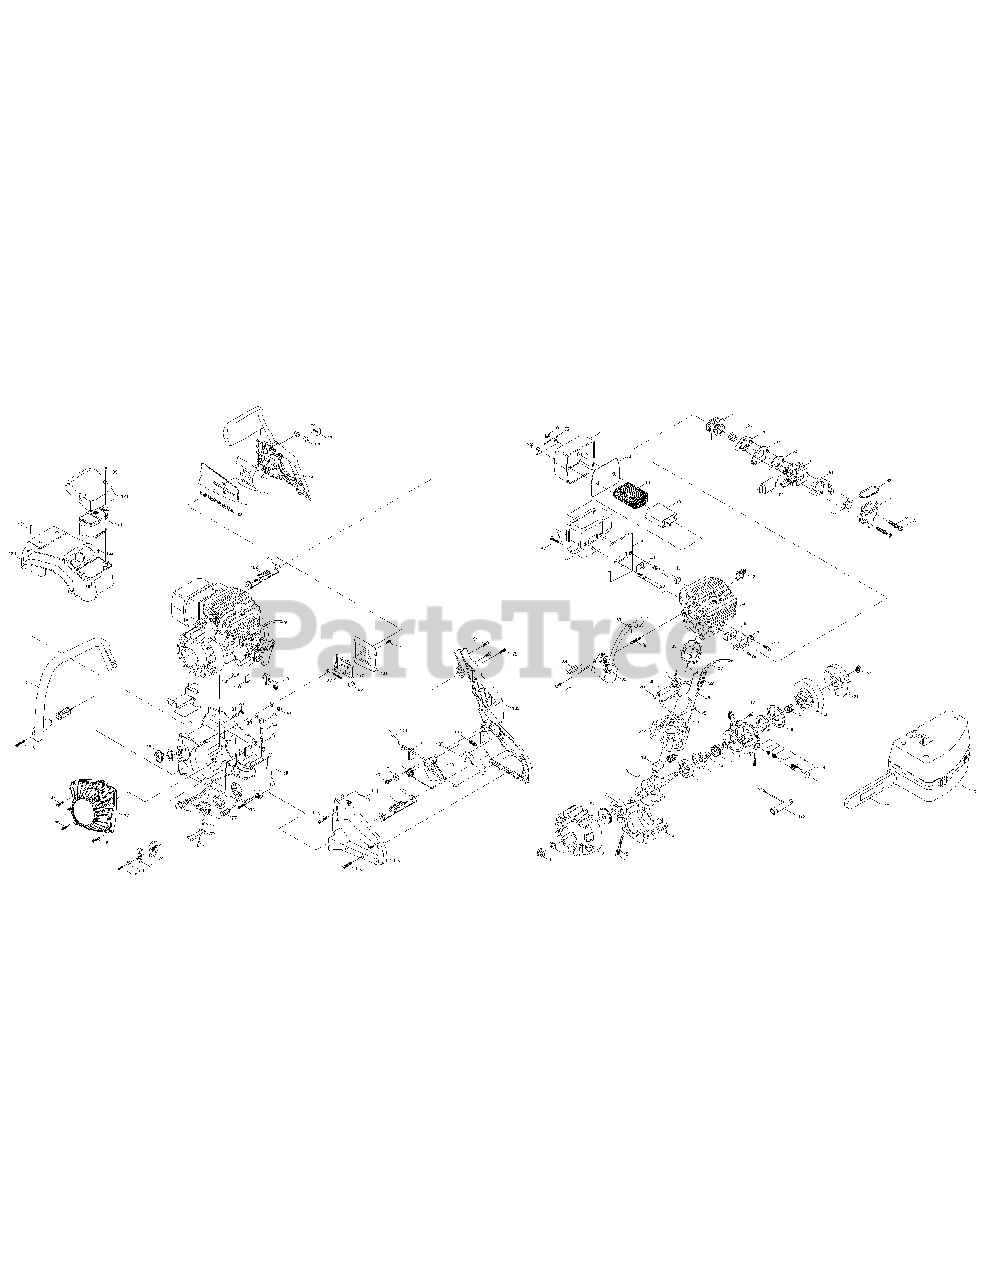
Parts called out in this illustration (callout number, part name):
8	CRANKCASE LOWER
10	C'CHAFT/C'ROD ASSEMBLY
13	GEAR,WORM
16	PUMP ASSEMBLY
20	DRUM SPROCKET ASSEMBLY
21	CLUTCH ASSEMBLY
23	CRANKCASE UPPER
24	FITTING, PULSE LINE
26	CLAMP, WIRE HOSE
27	CONDUIT, FLEX
32	RING,PISTON
35	IGNITION ASSEMBLY
38	SCREW
42	SPARK PLUG
46	MUFFLER BODY ASSEMBLY
51	COVER MUFFLER
52	LOCKPLATE
54	BOOT, CARBURETOR
59	CARBURETOR
67	STARTER ASSEMBLY
74	PRIMER,REMOTE
77	FITLTER, FUEL
80	FUEL/OIL TANK ASSEMBLY
81	VALVE DUCKBILL
91	PLATE, FLANGE
93	18'' CHAIN
93	20'' CHAIN
96	CHAIN BRAKE ASSEMBLY
99	CHOKE ASSEMBLY
100	ROD, CHOKE
102	ISOLATOR ASSEMBLY
103	CABLE ASSEMBLY
107	RELEASE, TRIGGER
110	CABLE ASSEMBLY
113	ISOLATOR ASSEMBLY
114	WIRE ASSEMBLY
115	COVER ASSEMBLY, HANDLE
119	HANDLE ASSEMBLY
120	COVER ASSEMBLY, HANDLE
122	SCREW
123	AIR CLEANER ASSEMBLY
126	CARRY CASE
